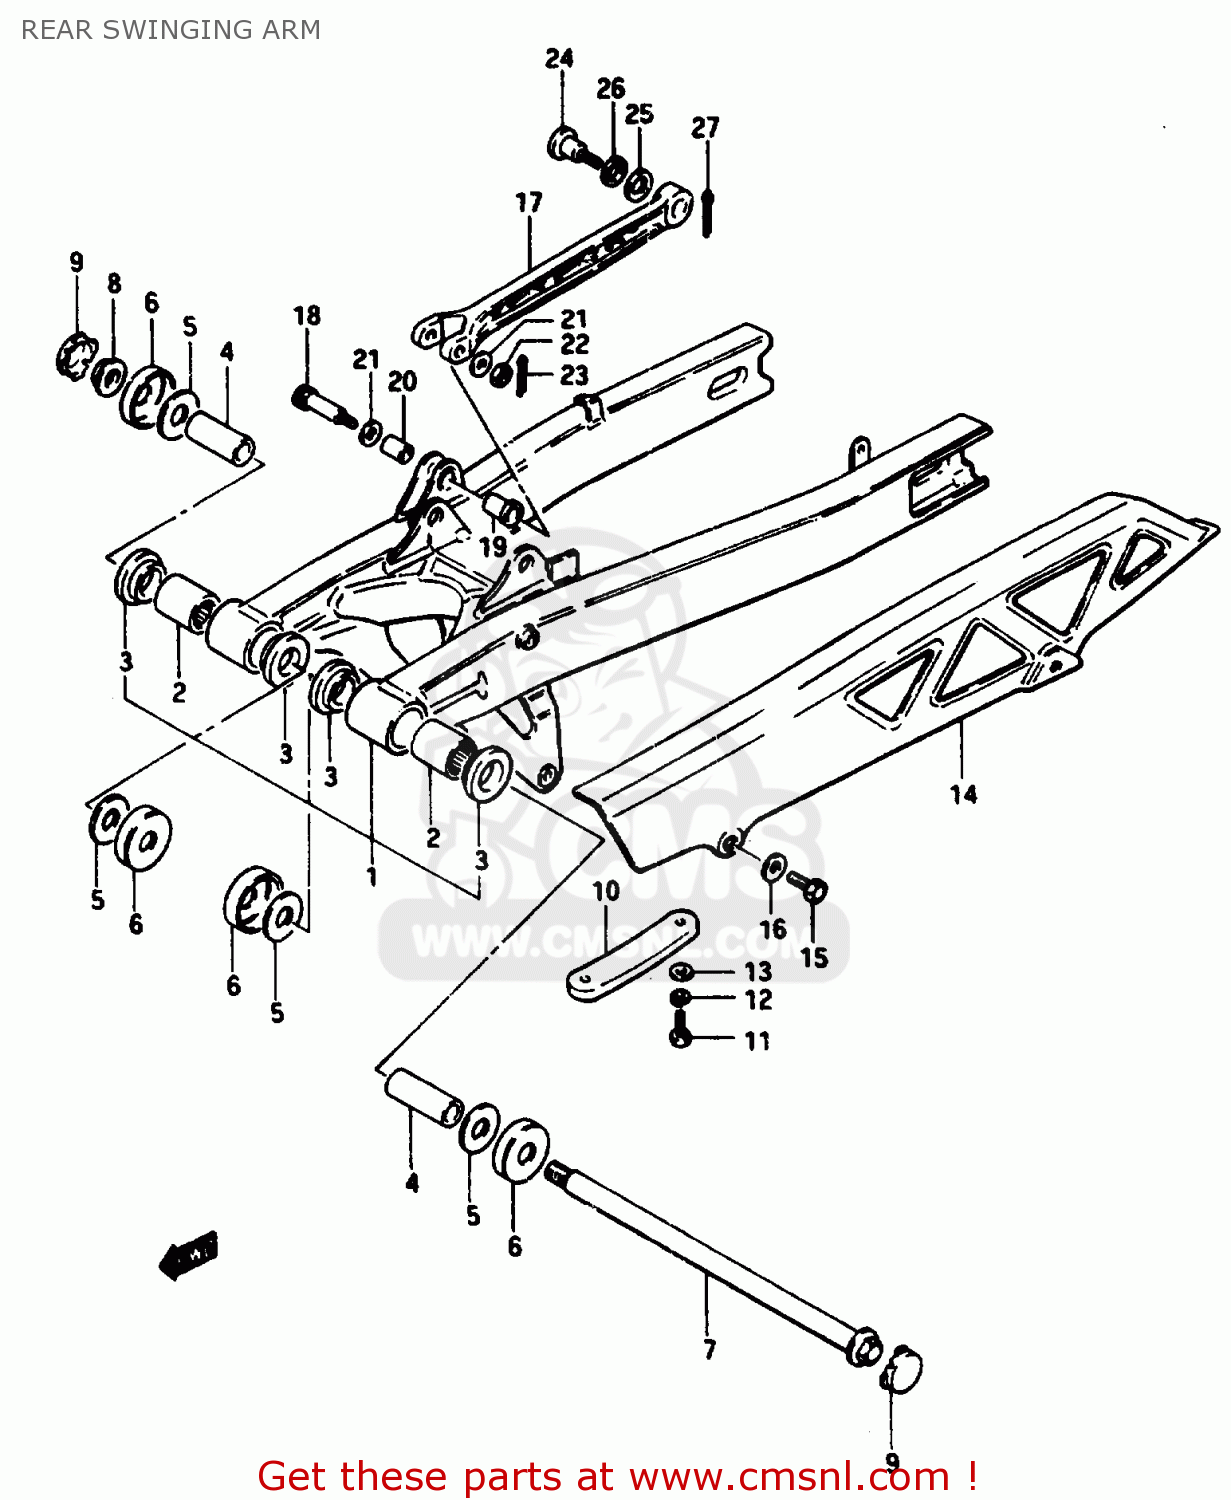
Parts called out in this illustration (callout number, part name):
1	ARM,REAR SWING
2	BEARING(25X33X30)
3	BUSHING
4	SPACER,RR SWINGING ARM PIVOT
5	WASHER
6	COVER,RR SWINGINGARM PIVOT
7	SHAFT,REAR SWING ARM
8	NUT
9	CAP,PIVOT
10	BUFFER,CHAIN TOUCH DEFENSE
11	BOLT
12	WASHER,LOCK
13	WASHER(6.5X18X1)
14	CASE,CHAIN
15	BOLT
16	WASHER
17	LINK,REAR TORQUE
18	BOLT 8X60
19	SPACER,REAR TORQUE LINK
20	SPACER,REAR TORQUE LINK
21	WASHER
22	NUT 8MM
23	PIN 20X20
24	BOLT,REAR TORGUE LINK,REAR
25	CUSHION
26	WASHER (18.5X28X2)
27	PIN 20X20
